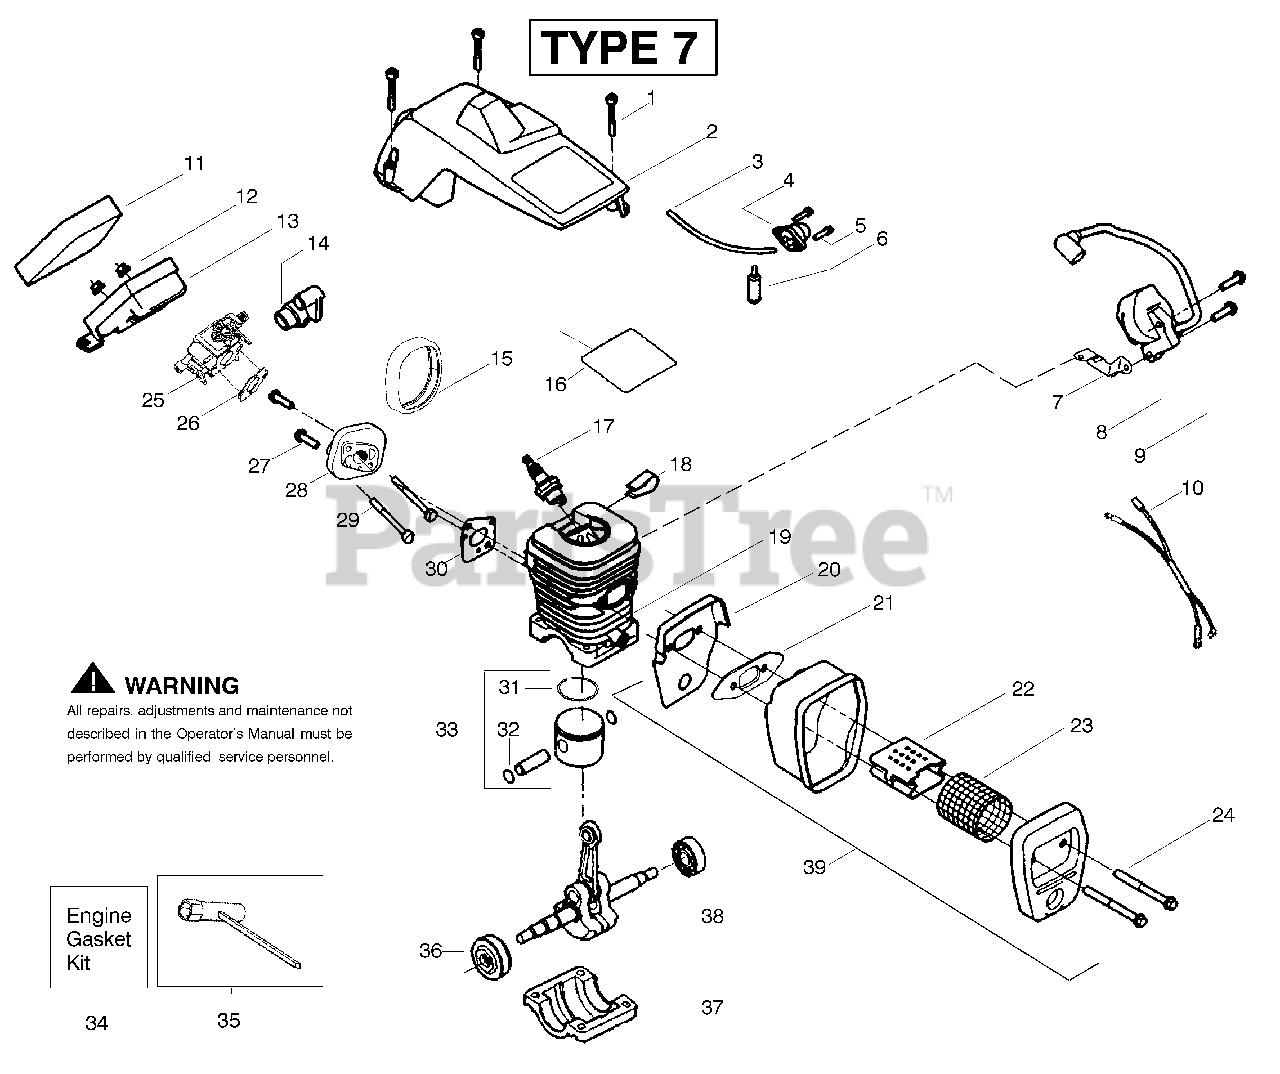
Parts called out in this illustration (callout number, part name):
2	Assy-Cylinder Shield
3	Kit-Fuel Line
4	Kit- Air Purge
6	Assy-Fuel Pick-up
7	Strap-Ground
8	Ignition Module
10	Assy-Wire Harness
11	Foam- Air Filter
13	Assy- Air Box
14	Grommet-Carb Adjust
15	Seal-Carb Adapter
16	Reflector-Heat
17	Spark Plug
18	Clip-High Tension Lead
19	Cylinder
20	Backplate-Muffler
21	Gasket-Muffler
22	Diffuser-Muffler
23	Screen-Spark
24	Bolt-Muffler
25	Kit-Carburetor Walbro (WT-89)
26	Gasket-Carb.
28	Carb. Adapter
30	Gasket- Adaptor
31	Ring-Piston
32	Retainer-Piston Pin
33	Kit-Piston
34	Kit-Engine Gasket
35	Bar Wrench
36	Assy-Seal & Bearing
37	Cap-Crankcase
38	Assy-Crankshaft
39	Assy-Muffler
